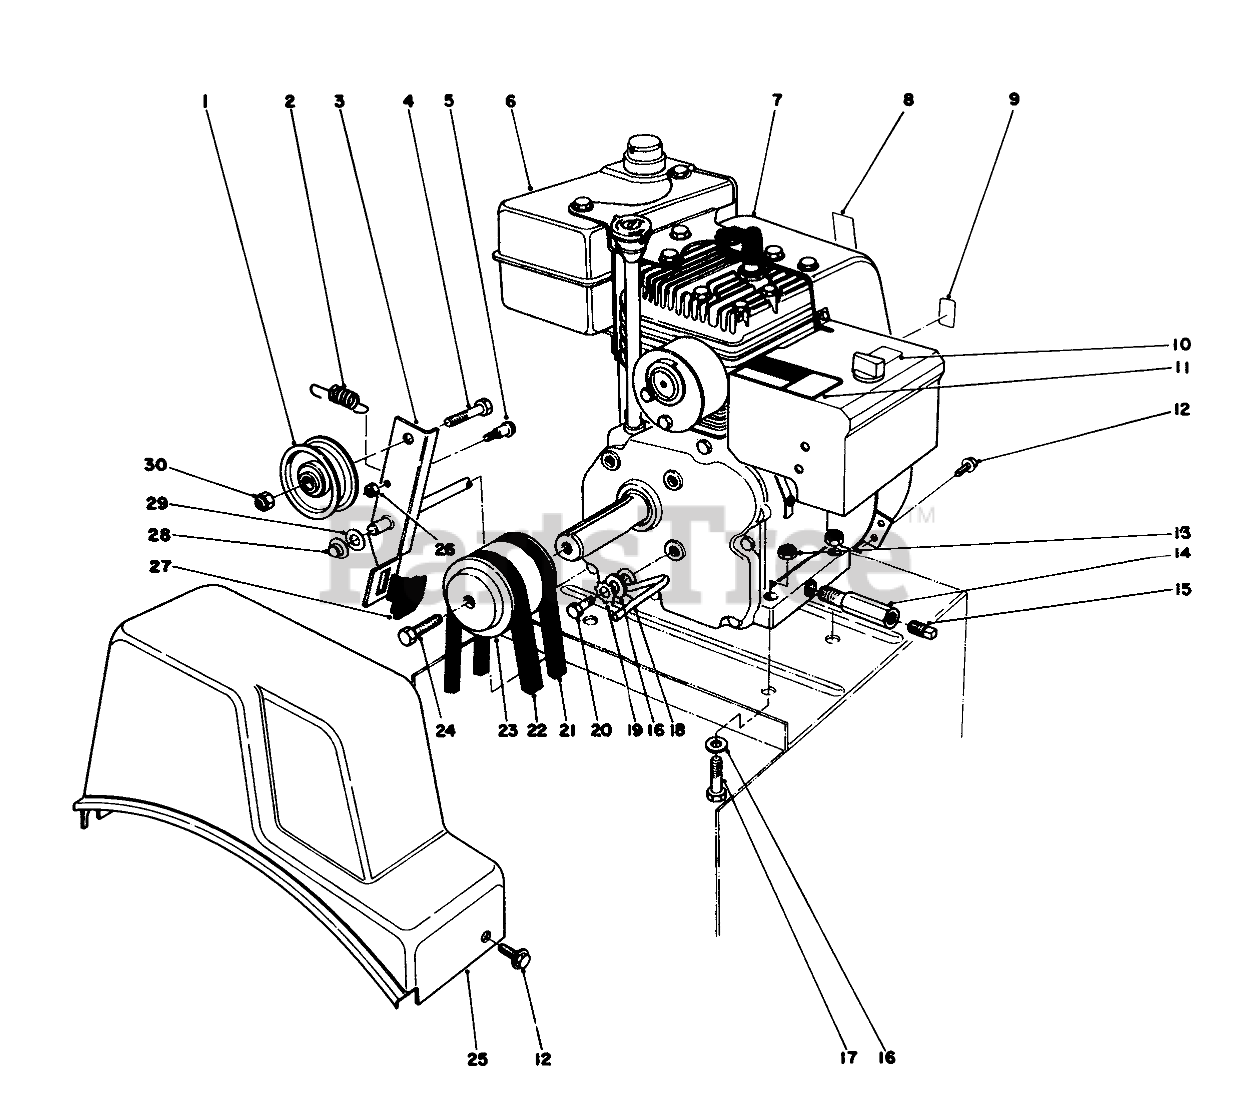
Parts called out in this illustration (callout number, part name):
1	PULLEY-IDLER
2	SPRING
3	Auger Clutch Rod Assembly (Incl. Ref. #27)
4	SCREW-HH
5	BOLT-SHOULDER
6	GAS TANK 2 QT W CAP
7	Engine
8	PRIMER DECAL
9	DECAL THROTTLE
10	CHOKE DECAL
11	HOT SURFACE DECAL
12	Bolt 1/4-20
13	NUT-LOCK, NI
14	PIPE-NIPPLE
15	CAP-PIPE
16	WASHER-PLAIN
17	SCREW-HH
18	RETAINER-BELT
19	WASHER-LOCK
20	SCREW-HH
21	V BELT-3L, TRACTION
22	V-BELT (29.50 INCH)
23	PULLEY-ENGINE
24	SCREW-SPECIAL
25	COVER-BELT
26	NUT-LOCK, CONE
27	Brake Pad
28	RETAINER-PUSH ON
29	WASHER-FLAT
30	NUT-LOCK, CONE
